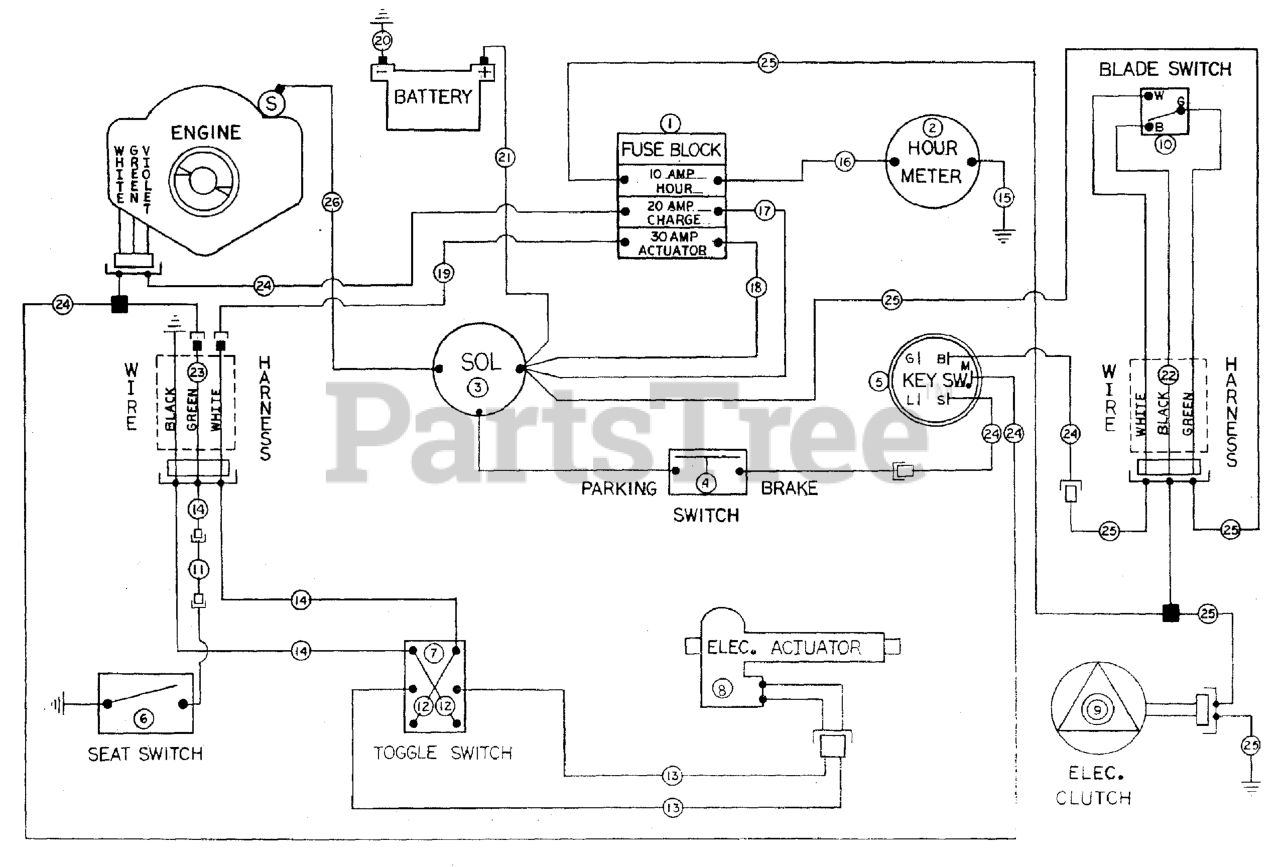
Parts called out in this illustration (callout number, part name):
1	Fuse Block
1	10 Amp Fuse
1	20 Amp Fuse
1	30 Amp Fuse
2	HOUR METER
3	SOLENOID, Starter
4	Parking Brake Switch Assembly
5	SWITCH, Ignition
6	Seat Switch Assembly
7	Toggle Switch
8	Electric Actuator
9	CLUTCH, Electric, 1" Shaft
10	Toggle Switch
11	Green Alpha Cable to Seat Switch
12	Red Corner to Corner Toggle Switch
13	Toggle Switch to Actuator Harness
14	Actuator Switch to Alpha Cable Harness
15	Blue (-) Hour Meter to Ground
16	Blue Fuse Block to Hour Meter (+)
17	Red Fuse Block to Solenoid
18	White Fuse Block to Solenoid
19	White Alpha Cable to Fuse Block
20	Negative Battery Cable
21	Positive Battery Cable
22	Alpha Cable - Electric Clutch
23	Alpha Cable - Electric Actuator
24	Key Switch / Charge Harness
25	Electric Clutch / Alpha Cable Harness
26	Solenoid to Starter
